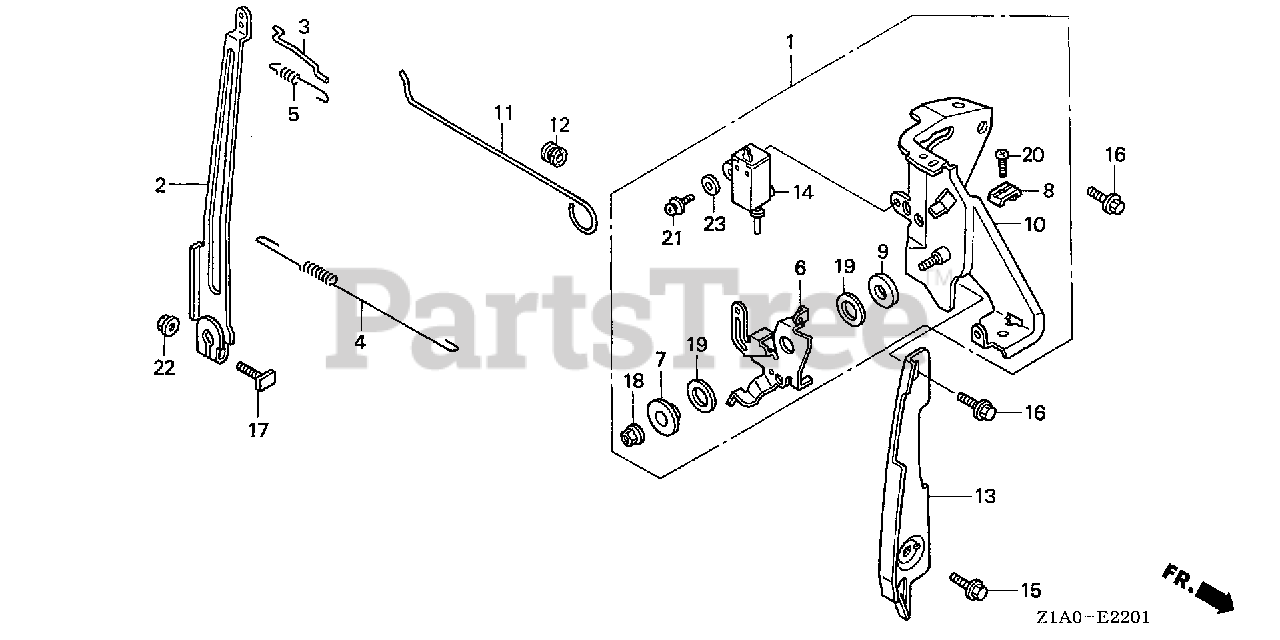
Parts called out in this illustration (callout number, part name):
1	CONTROL ASSY.
2	ARM, GOVERNOR
3	ROD, GOVERNOR
4	SPRING, GOVERNOR
5	SPRING, THROTTLE RETURN
6	LEVER, CONTROL
7	WASHER, CONTROL LEVER
8	HOLDER, CABLE
9	SPACER, CONTROL LEVER
10	BASE, CONTROL
11	ROD, CHOKE CONTROL
12	GROMMET, CHOKE ROD
13	PLATE, SIDE
14	SWITCH ASSY., ENGINE STOP (N.O)
15	BOLT, FLANGE (6X12) (CT200)
16	BOLT, FLANGE (6X14)
17	BOLT, GOVERNOR ARM
18	NUT, SELF-LOCK (6MM)
19	WASHER (12.5MM)
20	SCREW, PAN (5X16)
21	SCREW-WASHER (4X12)
22	NUT, FLANGE (6MM)
23	WASHER, PLAIN (4MM)
